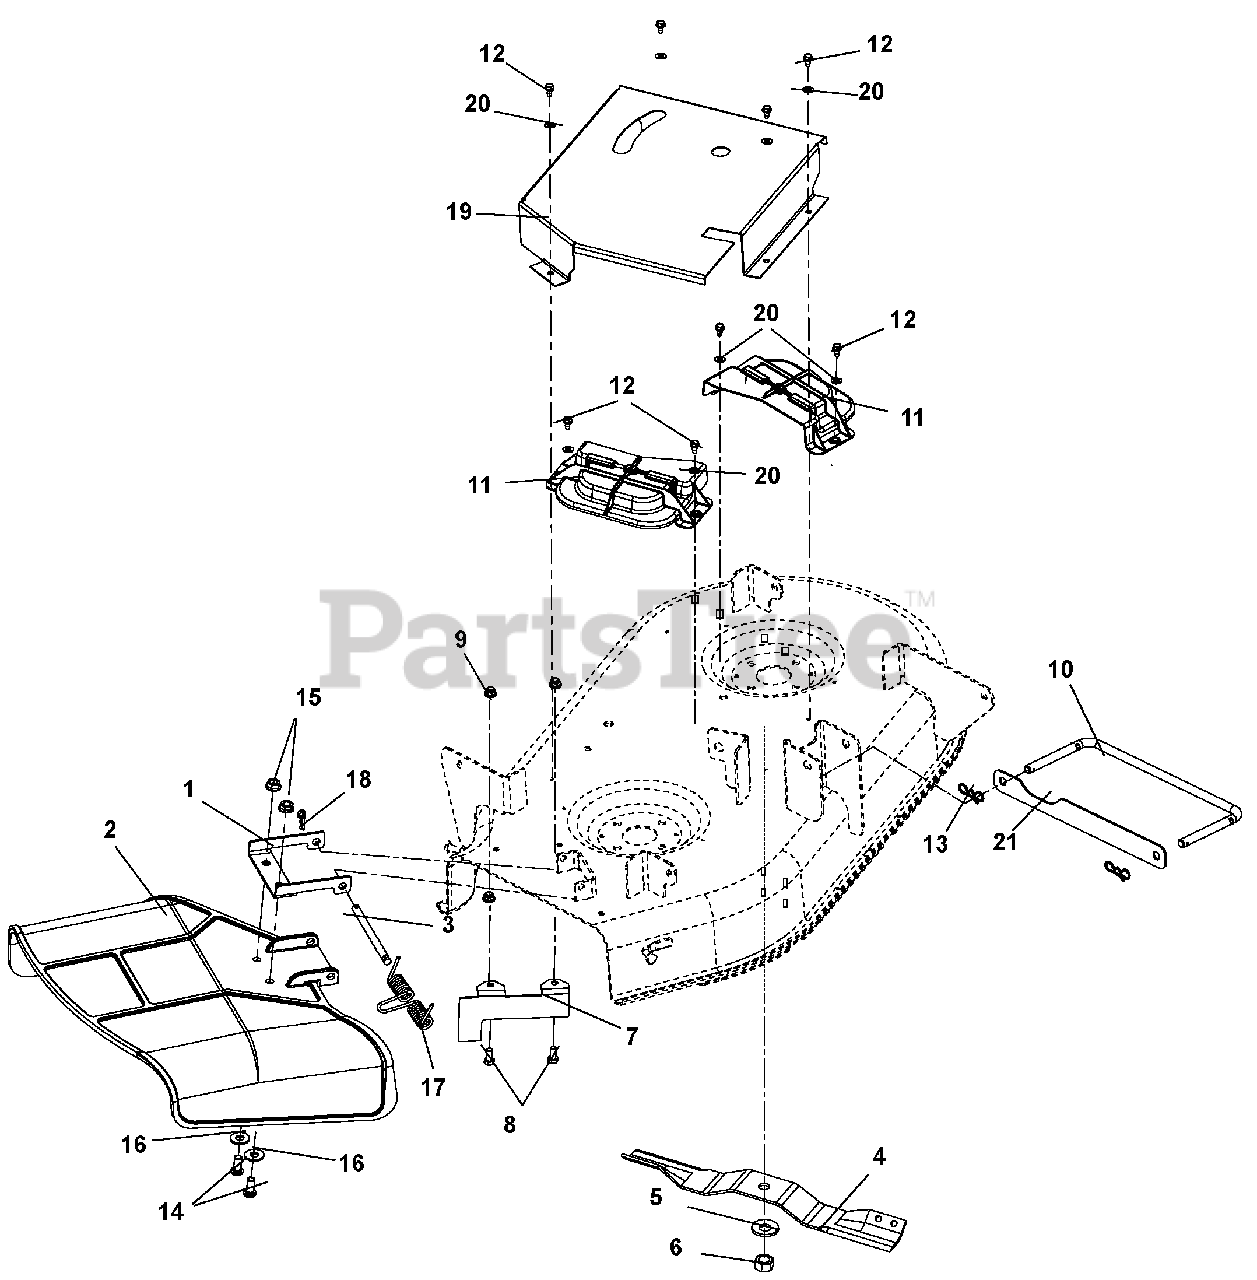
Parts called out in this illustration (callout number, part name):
1	Chute Reinforcement
2	Molded Chute
3	Pin, 5/16 x 3.88"
4	Blade, 17.34 OS Mulch
5	Washer, Beveled .63 x 1.625 x .14
6	Nut, Hex .62-18
7	Bracket, Baffle Discharge 34"
8	Bolt, Hex .31-18 x .75
9	Nut, .31-18 Nyloc Flange
10	Wireform, Drag Link
11	Molded Cover, Belt
12	Screw, Tapping .25-20 x .50 LGHWH TR YZ
13	Pin, Bow Tie Locking Cotter .091 x 1.875
14	Screw, .31-18 x .75
15	Nut, Locking Top Flange .31-18
16	Washer, Flat Steel .38 x .875 x .083
17	Spring, Torsion
18	Pin, Hair .08 x .18 x 1.18
19	Guard, 34" Zoom/ZT CE Belt
20	Nut, Push .25x.5 O.D.
21	Strap, Drag Link
